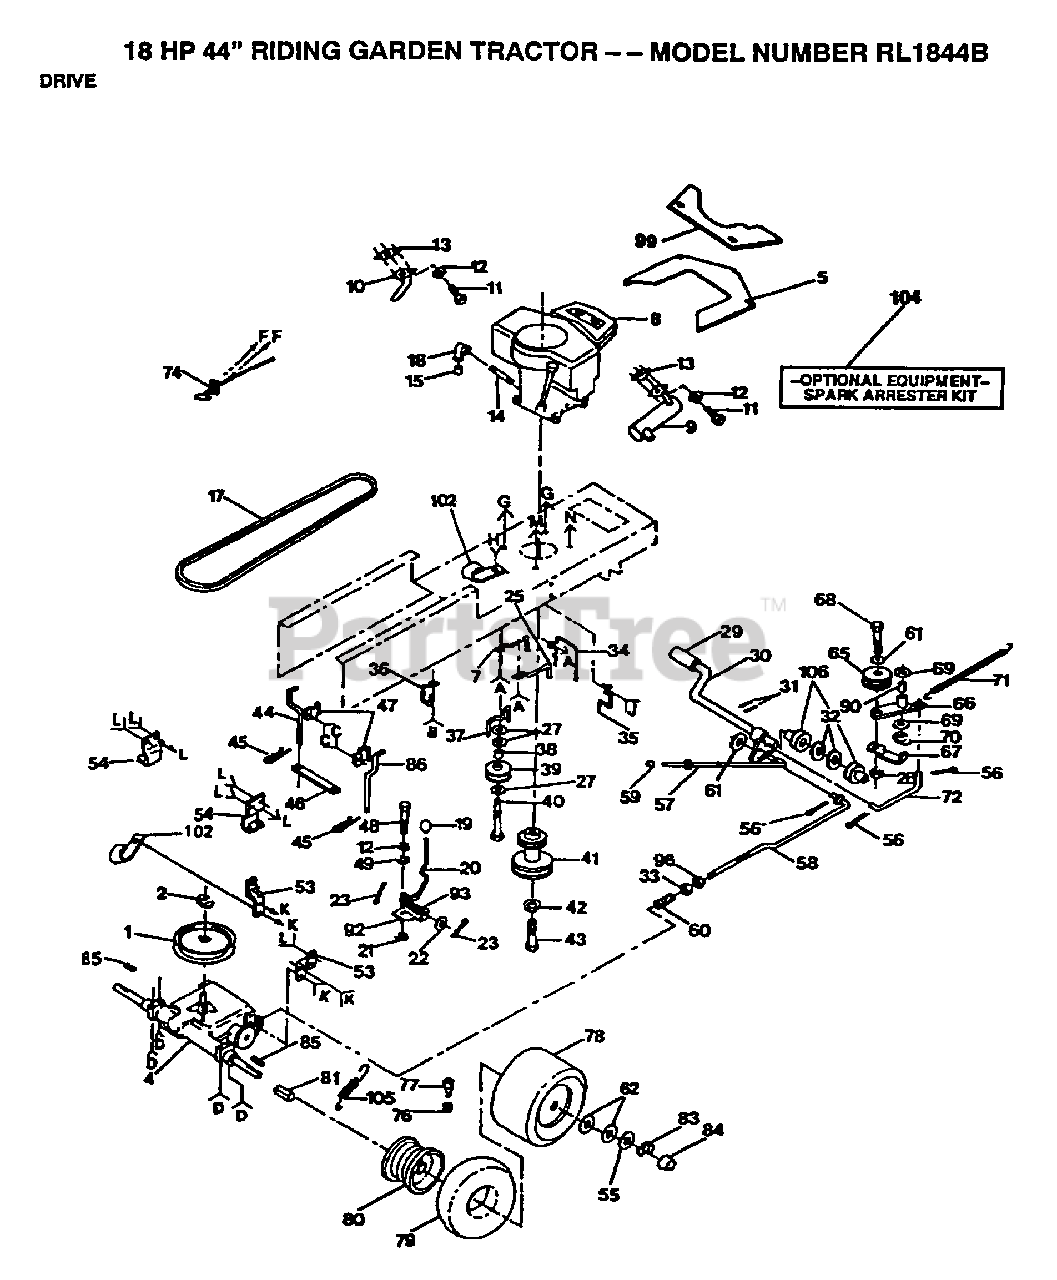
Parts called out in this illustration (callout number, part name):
1	"PULLEY,TRANSAXLE"
2	RING
5	SHIELD HEAT FRT
6	WASHER
7	KEEPER BELT ENGLH
10	EXHAUST TUBE T
12	LOCKWASHER
14	PIPE NIPPLE LT
18	ELBOW
19	KNOB T (1/2-HOLE)
20	ROD SHIFTER
21	WASH-SHFT PLT LT
22	WASHER
23	PIN COTTER 1/8
24	SCREW
25	"KEEPER,BLT ENG LT"
26	BOLT
27	WASHER
29	PEDAL COVER T
32	WASHER LT
33	NUT
34	BELT GUIDE
35	BELT GUIDE
37	BELT KEEPER LT
38	SPACER T
39	PULLEY.IDLER.FLAT
40	BOLT
42	LOCKWASHER
43	BOLT
45	SPRING.RETAINER
46	STRAP LOCATOR
47	CLAMP LT
49	WASHER LT
50	BOLT
53	STRAP TORQUE
54	BRACKET LT
55	WASHER
56	COTTER PIN
57	ROD BRAKE PARK
58	BRAKE ROD LT
59	PLUNGER CAP T
60	SPRING ROD LT
61	WASHER
62	WASHER
66	ARM IDLER
67	RETAIN BELT
69	WASHER LT
70	KLIP RING
71	"SPRING, RETURN LT"
72	"LINK, CLUTCH T"
75	SCREW LT
76	VALVE CAP
77	VALVE STEM LT
79	TUBE.18X9.5-8
81	SPACER LT
83	E-RING LT
84	HUB CAP
85	SQUARE KEY
87	SCREW LT
90	"LY, BEARING"
92	PLATE SHIFT LT
93	SPRING LT
94	LOCKWASHER
95	NUT
96	NUT
98	WASHER
99	REAR BAFFLE T
101	SCREW
102	CLIP T
106	NYLON BEARING
